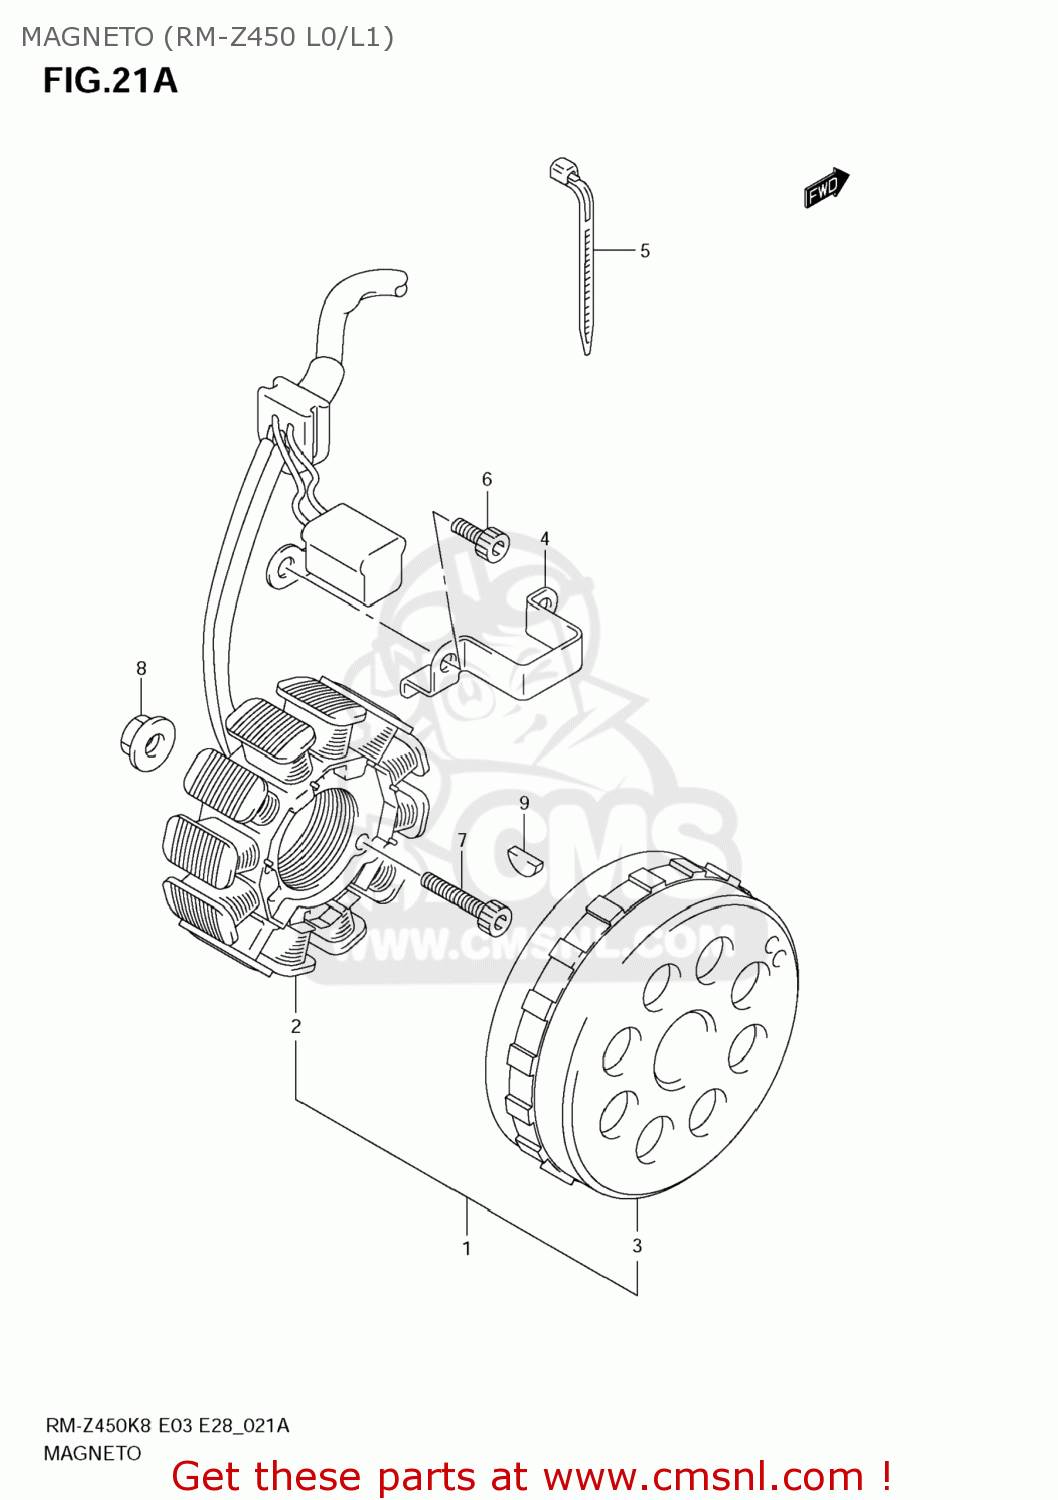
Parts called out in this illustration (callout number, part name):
1	MAGNETO ASSY
2	STATOR ASSY
3	ROTOR ASSY
4	CLAMP,MAGNETO LEAD
5	CLAMP(L:125)
6	BOLT
7	BOLT
8	NUT
9	KEY
